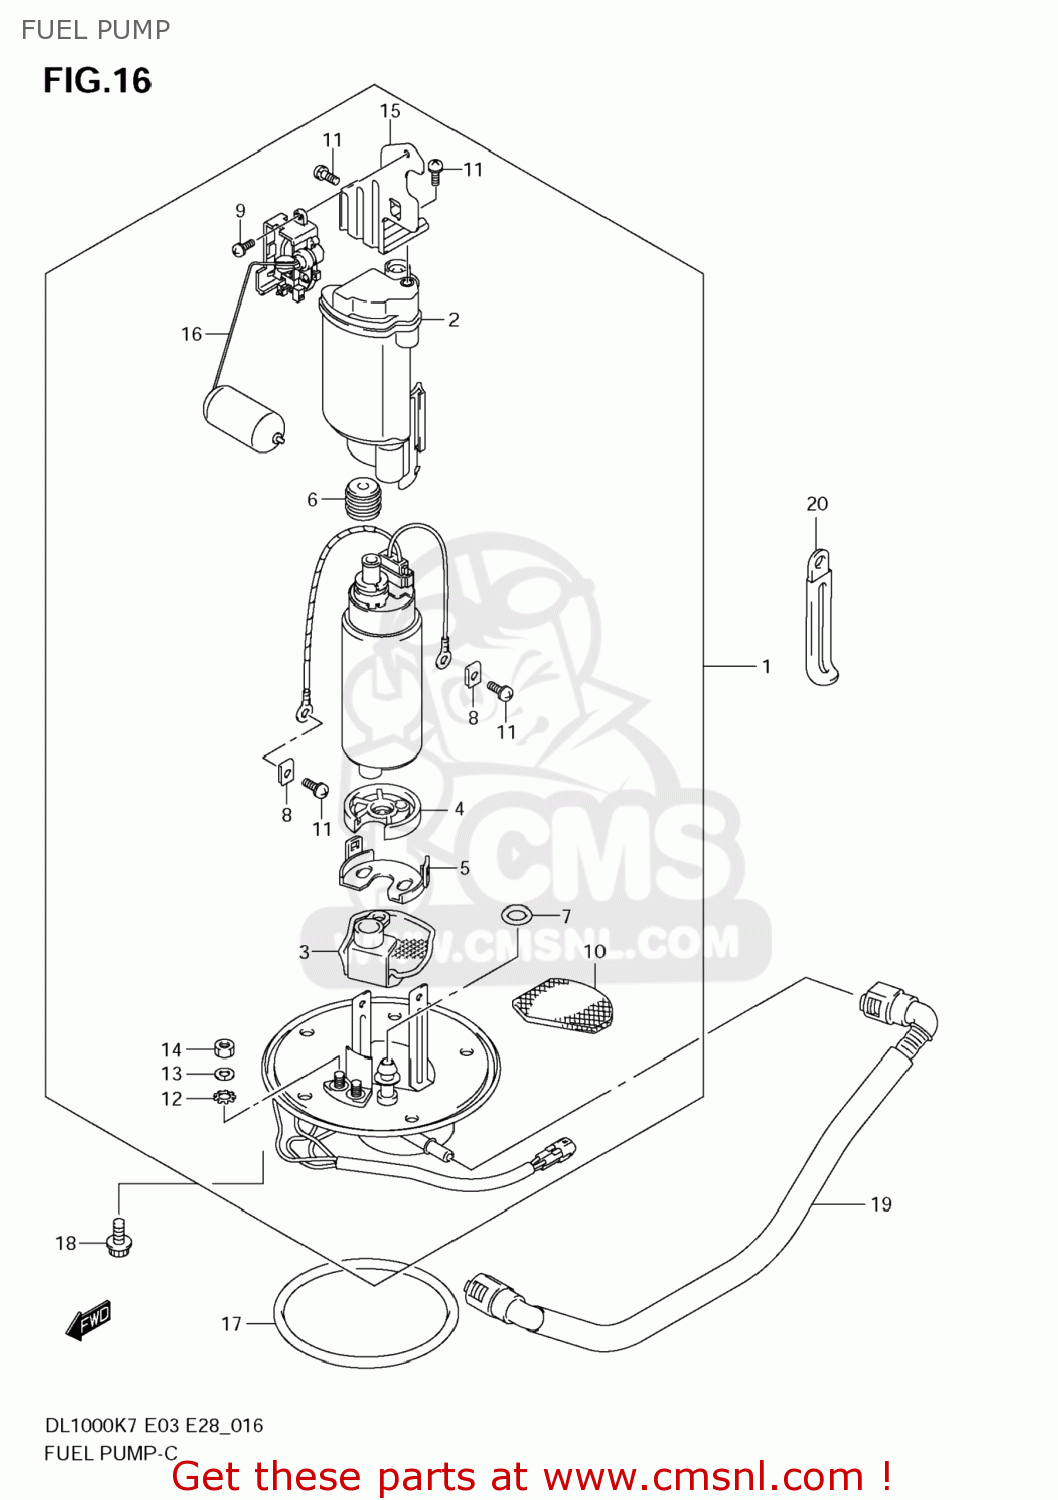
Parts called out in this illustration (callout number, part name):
1	PUMP ASSY,FUEL
2	FILTER,FUEL
3	STRAINER,FUEL PUMP
4	CUSHION
5	HOLDER,FUEL PUMP
6	BUSH,FUEL PUMP
7	O RING
8	NUT
9	SCREW
10	SHEET
11	SCREW
12	WASHER
13	WASHER,SPRING
14	NUT
15	BRACKET,FUEL GAUGE
16	GAUGE ASSY,FUEL LEVER
17	O RING,FUEL PUMP
18	BOLT
19	HOSE COMP,FUEL
20	CLAMP(L:45)
